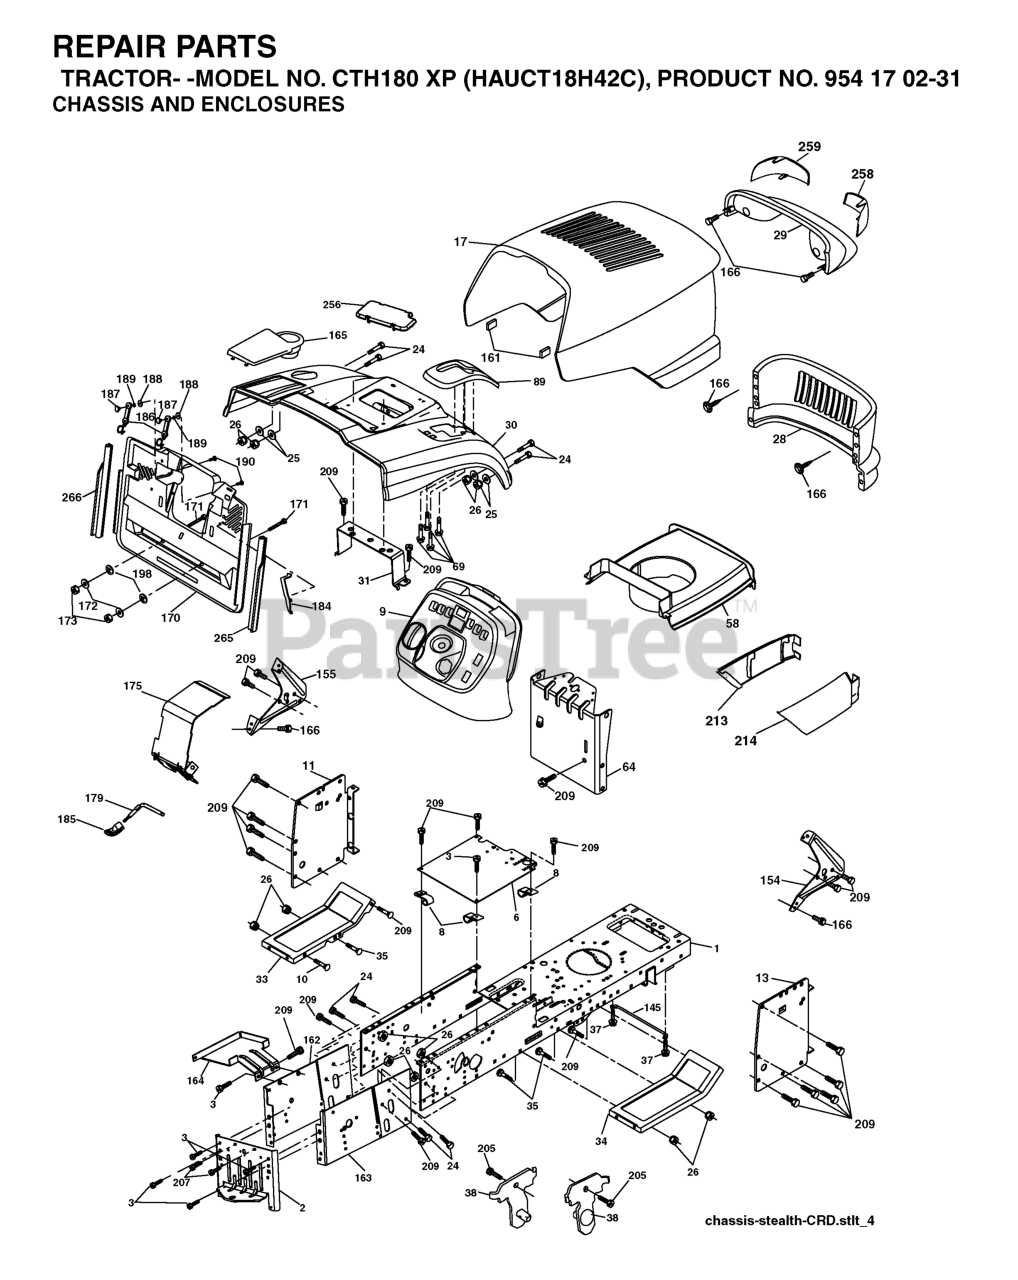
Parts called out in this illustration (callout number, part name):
2	DRAWBAR
3	SCREW 3/8-16X3/4
6	PLATE
8	CLIP,INSULATOR
9	DASH, PLASTIC
10	BOLT D
11	PANEL DASH LH
13	PANEL DASH RH
16	NUT
17	HOOD
24	BOLT
25	WASHER
26	NUT
28	GRILLE.STEALTH P/L.YTGT.GREY
29	LIGHTBOX.ASM.STV.DL.INC.HUSQ
31	BRACKET SUPPORT FENDER
33	FOOTREST PNT LH
34	FOOTREST PNT RH
35	BOLT
37	Screw 5/16-18 x 1/2 Hex, Self Tapping 5/16-18 x 1/2
38	BRACKET ASM PIVOT MOWER REAR
64	DASH.LOWER.YT.2003
69	SCREW.HI-LO.CONSOLE
89	COVER.BATTERY.CRD.GREY
145	ROD PIVOT CHASSIS/HOOD
161	EXTRUSION BUMPER (3 2) (2 2)
162	BRACKET
163	BRACKET EXTEN CHASSIS RH CRD
165	RP.COVER.BATTERY.CRD.GREY
166	SCREW
171	BOLT
172	WASHER
175	DOOR TRAP
179	ROD PIVOT FBI
184	BRACKET.ACTUATOR.BAGGER.SRD
186	LATCH ASSY
187	WELDNUT
189	LOCKWASHER #10
190	SCREW
205	SCREW LT
207	SCREW, 5/16-18 X 1/2
213	SKIRT GRILLE LH
214	SKIRT GRILLE RH
256	COVER FENDER CRD
258	LENS RH
259	LENS LH
265	SEALING
266	SEALING
